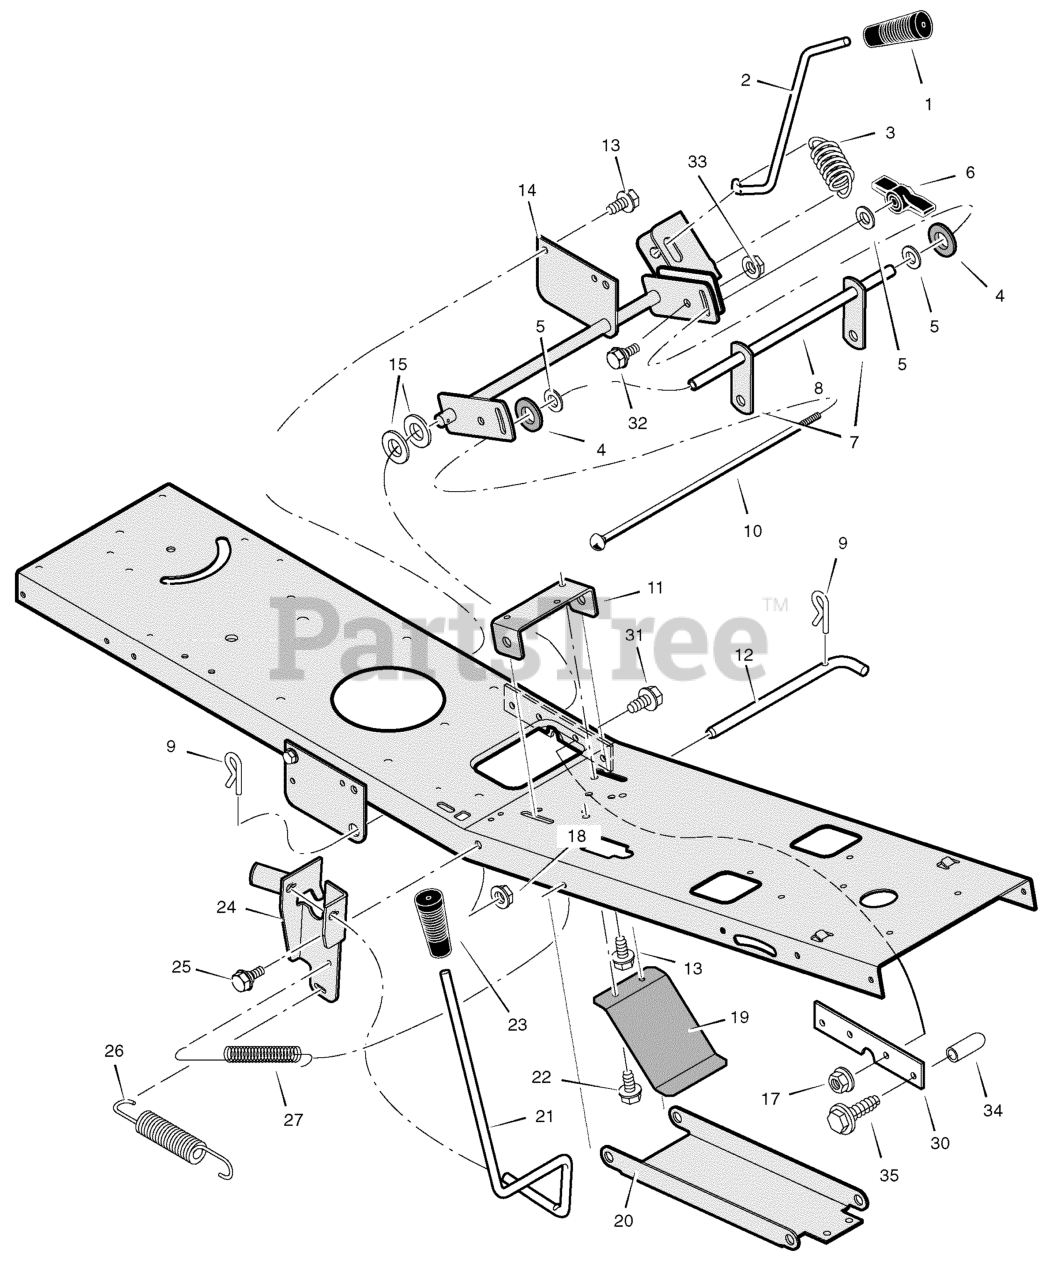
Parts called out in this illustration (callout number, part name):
1	Grip, Lift Lever
2	Lever, Lift
3	Spring, Extension
4	Pad, Friction
5	Washer
6	Wingnut
7	Link, Lift
8	Tube, Spacer
9	Pin, Hair
10	Bolt, Carriage
11	Bracket, Front Hanger Pivot
12	Pin, Front Hanger
13	Screw
14	Arm Assembly, Lifter
15	Washer
17	Nut, Flange
18	Nut, Flange
19	Spring, Leaf
20	Hanger, Front
21	Lever, PTO
22	Screw
23	Grip, PTO
24	Bracket, PTO
25	Bolt, Shoulder
26	Spring, Extension
27	Spring, Extension
30	Plate, Reinforcement
31	Screw
32	Bolt, Shoulder
33	Nut
